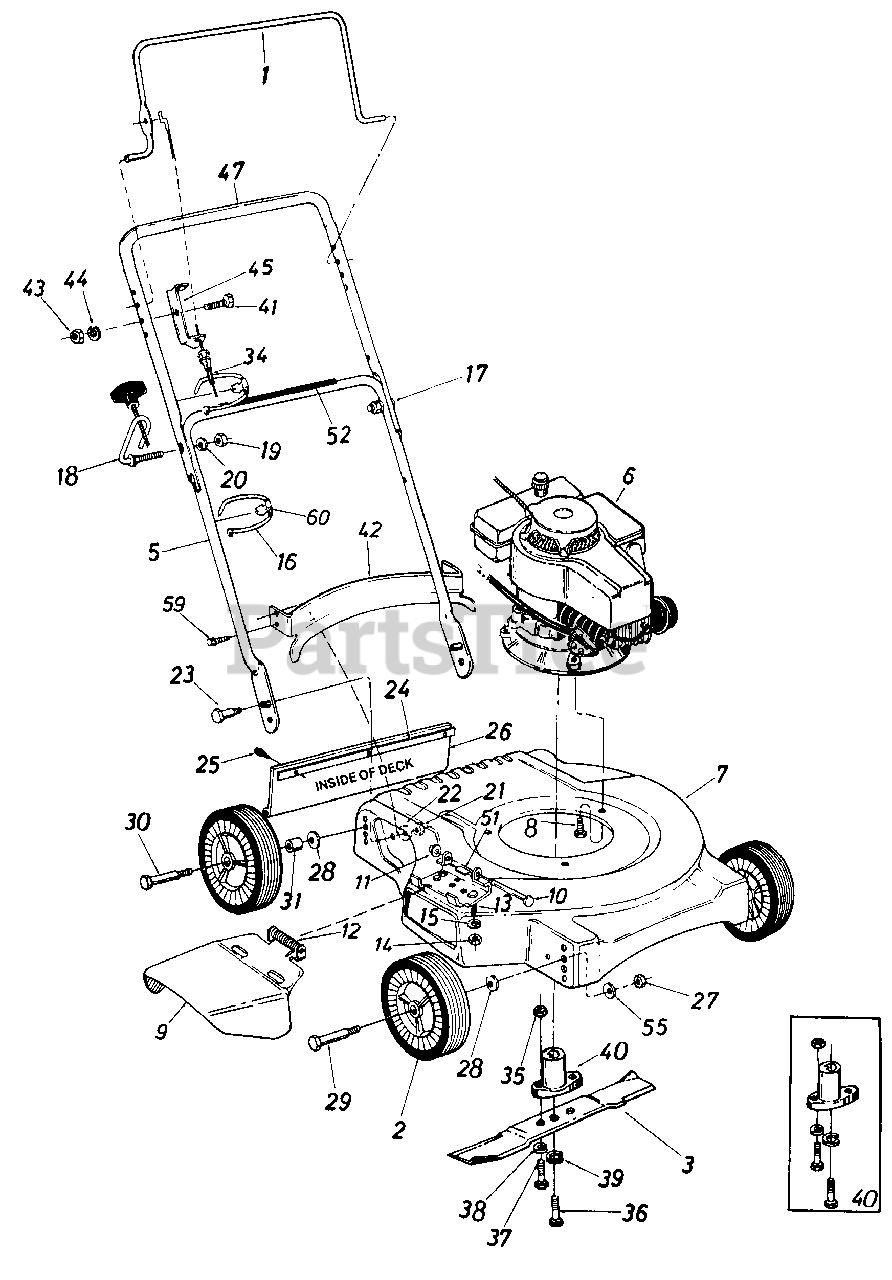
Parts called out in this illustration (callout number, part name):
1	Control Handle
2	Wheel Ass'y.
3	20" Blade
5	Lower Handle
6	Engine
9	Chute Deflector Ass'y.
10	Pivot Pin
11	Cap Speed Nut 1/4" Rod
12	Torsion Spring
13	Hex Bolt 1/4-20 X .50" Lg.
14	Hex Nut 1/4-20 Thd.
15	L-Wash. 1/4" I.D.
16	Cable Tie
17	Curved Carriage Bolt 5/16-18 x 1.38" Lg.
18	Rope Guide Bolt
19	Hex Nut 5/16-18 Thd.
20	L-Wash. 5/16" I.D.
21	Hex Ins. L-Nut 5/16-18 Thd.
22	Bell-Wash. .345" I.D. x .88" O.D.
23	Shld. Bolt .437" Dia. x .268" Lg.
24	Retainer Strip
25	Hex Wash. Hd. Self-Tap Scr. 1/4" X .62" Lg.
26	Rear Flap Ass'y.
27	Hex Nut 3/8-16 Thd.
28	Bell-Wash. .400" I.D. x .88" O.D.
29	Shld. Bolt
30	Shld. Bolt
31	Spacer
34	Control Cable 43.0" Lg.
35	Hex Nut 5/16-24 Thd.
36	Hex Bolt 3/8-24 x 1.00" Lg. (Grade 5)
37	Hex Bolt 5/16-24 x 1.00" Lg. (Grade 5)
38	L-Wash. 5/16" I.D.
39	L-Wash. 3/8" I.D. Heavy Duty
40	Blade Adapter Kit
41	Hex Bolt 1/4-28 X 1.75" Lg.
42	Rear Baffle
43	Hex Nut 1/4-28 Thd.
44	L-Wash. 1/4" I.D.
45	Cable Mounting Brkt.
47	Upper Handle
51	Hinge Plate
52	Instruction Label Handle
55	Bell-Wash. .39" I.D. x 1.13" O.D.
59	Hex Tap Screw #10 x .50" Lg.
60	Cable Anchor
